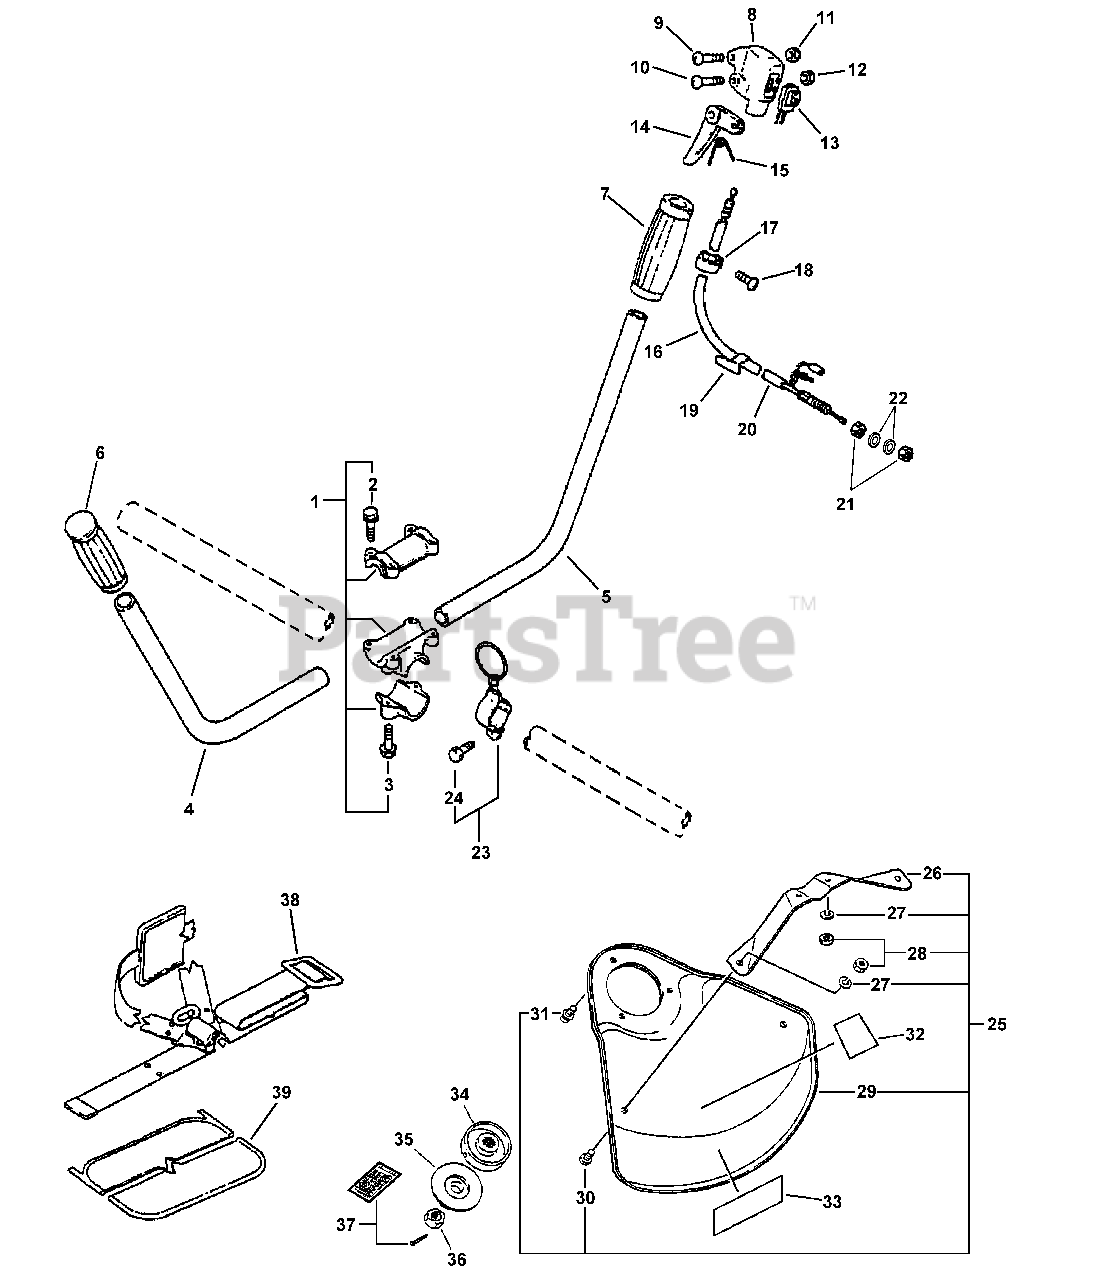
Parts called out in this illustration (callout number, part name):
1	BRACKET KIT, HANDLE
2	BOLT - 5×25
3	BOLT - 6×30
4	HANDLE, LEFT
6	GRIP, HANDLE
8	BODY, THROTTLE CONTROL
10	SCREW 5×25
11	NUT, LOCK M5
12	NUT M5
13	IGNITION SWITCH ASSY
14	TRIGGER, THROTTLE
16	CABLE, THROTTLE
18	SCREW 5×10
20	TUBE
21	NUT 6 MM
22	WASHER 6.5×11.5×0.8
23	HANGER ASSY, HARNESS
24	BOLT 5×12
25	SHIELD ASSY
26	BRACKET, SHIELD MOUNTING
27	WASHER, SPRING 5
28	NUT M5
29	SHIELD
30	SCREW 5×8
31	SCREW 5×10
32	LABEL - CAUTION
33	LABEL, ECHO
34	PLATE, ADAPTER - UPPER
35	PLATE, ADAPTOR - LOWER
37	PIN, COTTER 2×22
38	SHOULDER STRAP ASSY
39	PAD, HIP
